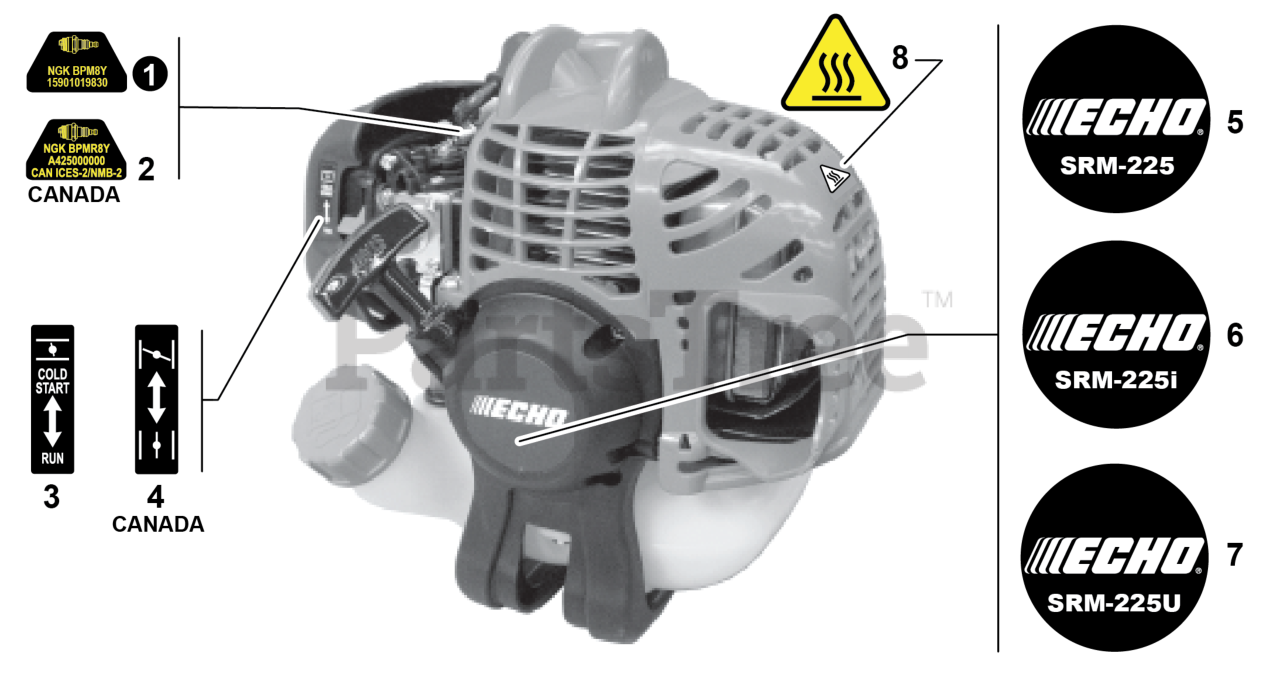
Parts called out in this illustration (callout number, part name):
1	LABEL - SPARK PLUG - BPM8Y
2	LABEL - SPARK PLUG - BPMR8Y
3	LABEL - CHOKE
4	LABEL - CHOKE
5	LABEL - STARTER - SRM-225
6	LABEL - STARTER - SRM-225I
7	LABEL - STARTER - SRM-225U
8	LABEL - CAUTION - HOT
